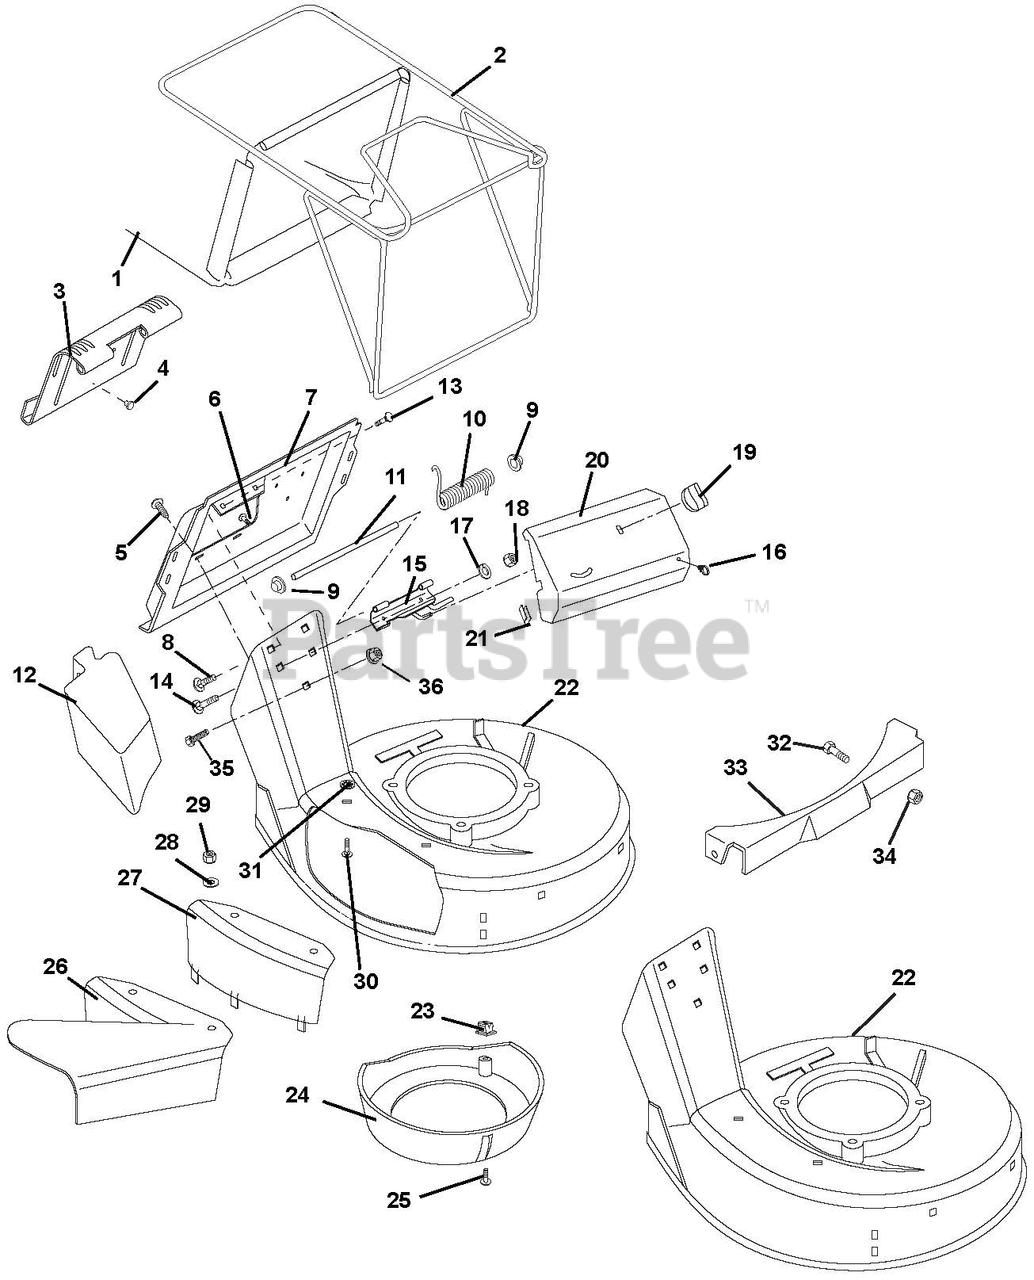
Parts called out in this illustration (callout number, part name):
1	BAG, CONSUMER BLACK 15 OZ/YD2
2	FRAME, BAGGER
3	CATCHER PLATE DOOR
4	BUTTON BUMPER
5	@SCR-TAP 12-24X.50 HWH TR YWZC
6	SCR-TAP 10-24X.375 TORX PHD YZ
7	CATCHER PLATE
8	@BLT-RHDSSQNK .25-20X.38 G2YZ
9	PUSH NUT, .25
10	SG-TORS .120X.68X3.09
11	DOOR PIN
12	MULCH MASTER MULCHER ACCESSORY
13	@NUT-SPNLK-FLG .25-20 YWZC
14	@BLT-RDHDSQNK .25-20X.75 G5YZ
15	HINGE BASE WELDMENT
16	SNAP-IN CLIP
17	WSHR-LK .250X.077 HVY YWZC
18	@NUT-HEX .25-20 YWZC
19	WING - NUT
20	COVER, DRIVE
21	TRIM BUMPER
22	MOWER PAN HEAD W/SFTYDECALS SP
22	MOWER PAN W/SAFETY DECALS PUSH
23	PLASTIC GROMMET
24	CENTER BAFFLE
25	SCR-TAP 10-16X.62 SLPH AB YWZC
26	SIDE DISCHARGE ASSEMBLY
27	COVER, SIDE DISCHARGE
28	@WSHR-FL-STL.406X.812X.065 YWZ
29	@NUT-LK-NYL .312-18 YWZC
30	BLT-RDHDSQSHK.31-18X.75 GR2 YW
31	NUT-PUSH .312
32	@BLT-RDHDSQNK .31-18X.50 G5YZ
33	PANEL-FRONT
34	@NUT-LK-TOP-FLG .31-18 YWZC
35	@BLT-HEX .38-16X.50 GR5 YWZC
36	@NUT-SPNLK-FLG .375-16 YWZC
